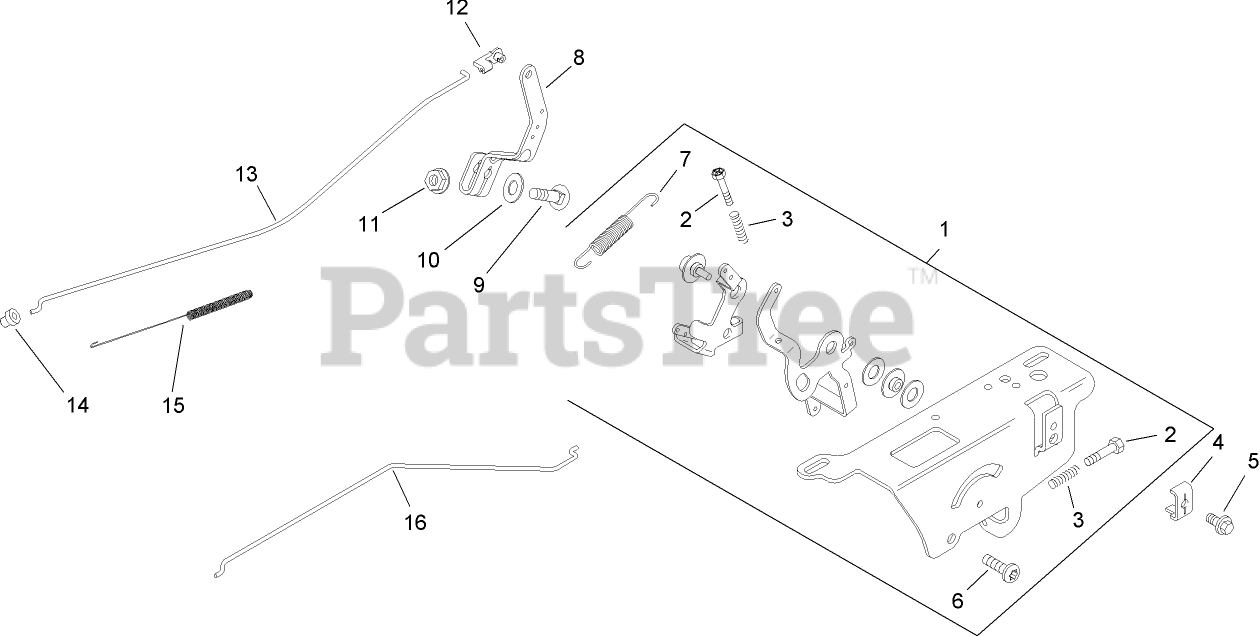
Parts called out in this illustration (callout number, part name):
1	Speed Control ASM
2	Screw-Thread Forming (M4x0.7x25)
3	Spring-Control, Speed
4	CLAMP-CABLE
5	SCREW-FLANGE, THREAD FORMING (M5X0.8X16)
6	Screw-Socket, 6 Lobed (Thread Forming, M6x1.0x20)
7	Spring-Governor
8	Lever-Governor
9	Bolt-Square Neck, Round Head (1/4-20x1)
10	Washer-Lock, Internal Tooth (1/4)
11	Nut-Flange, Hex (1/4-20)
12	BUSHING-RETAINING, LINKAGE
13	Linkage-Throttle
14	BUSHING-LINKAGE, THROTTLE
15	Spring-Linkage
16	Linkage-Choke (Single Wire)
